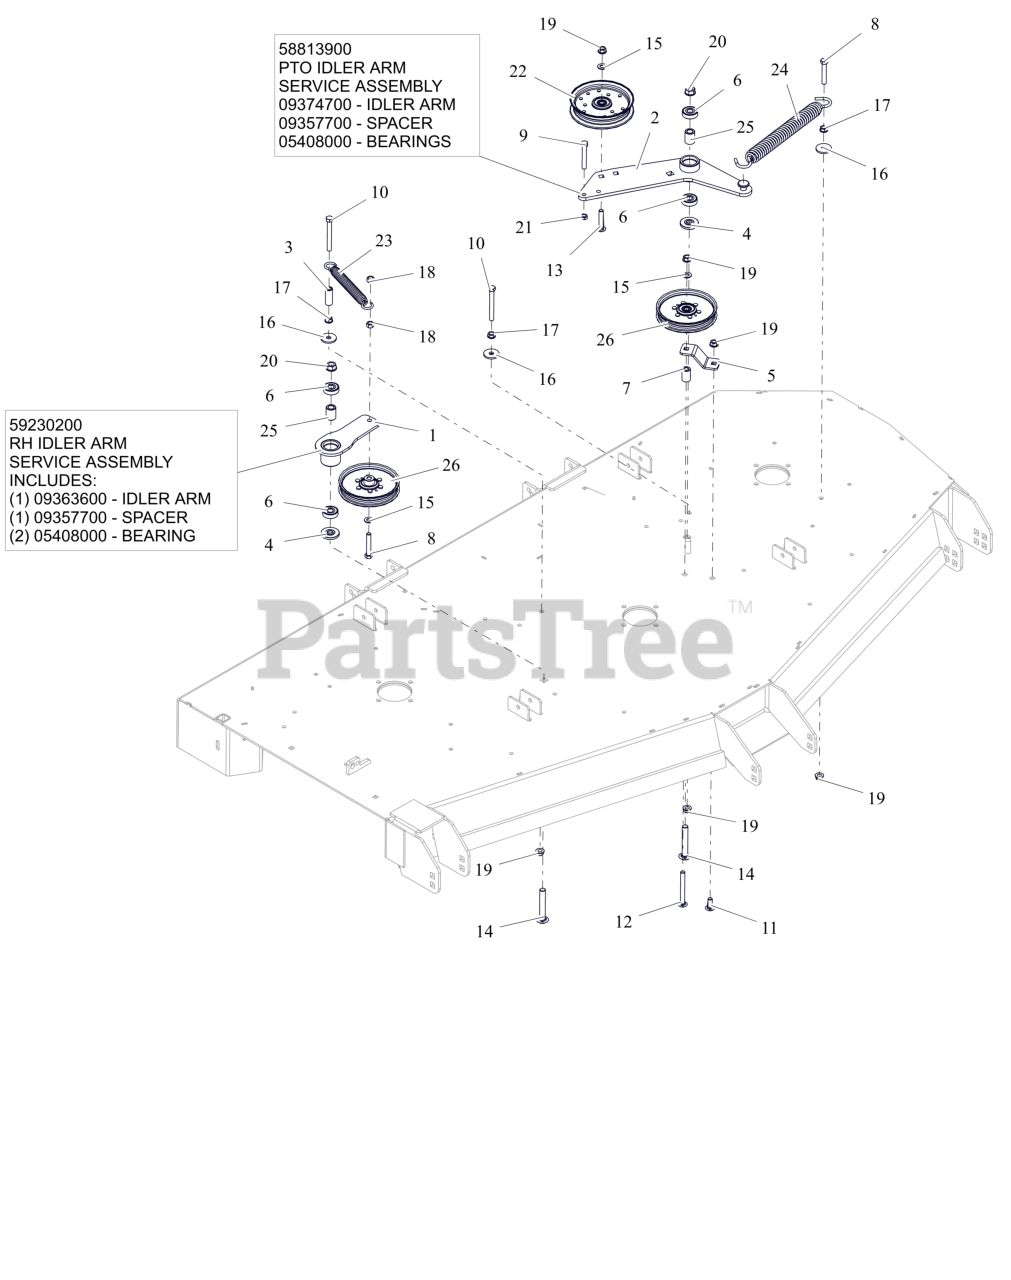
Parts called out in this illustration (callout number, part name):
1	WLDMT, DECK RH IDLER ARM
1	RH IDLER ARM
1	SPACER .510 X .75 X 1.1485
1	BRG-BALL .500X1.38X.437
2	WLDMT, IDLER ARM PT660
2	PTO IDLER ARM
2	SPACER .510 X .75 X 1.1485
2	BRG-BALL .500X1.38X.437
3	SPACER, .375IDX.625ODX1.66 PM
4	SPACER, IDLER ARM
5	PTO FIXED IDLER MTG BRKT -RED
6	BRG-BALL .500X1.38X.437
7	BUSHING, SLV .380X.750X1.190
8	BLT,HEX .38-16X2.25 G5 ZCC
9	BLT, HEX .38-16X2.50 G5 ZCC
10	BLT, HEX .38-16X3.25 G5 ZCC
11	BLT,RHSSN .38-16X1.00 G5 ZCC
12	BLT,RHSSN .38-16X3.50 G5 ZCC
13	BLT,RHSSN.375-16X2.00 G5 ZCC
14	BTL,RHSSN .500-13 X 3.25 G5 ZCC
15	WSHR,FLT .406X.812X.065 ZCC
16	WSHR,FLT .406X1.375X.135 ZCC
17	NUT, SPNLK-FLG .38-16 G5 ZCC
18	NUT-LK-CTR .38-16 ZC120
19	NUT-LK-CTR-FLG .375-16 GF ZCC
20	NUT-LK-CTR-FLG .500-13 GG ZCC
21	NUT-JAM .375-16 G2 ZCC
22	PULLEY, FLAT IDLER .500 X .375 W/BRG
23	SPRING, EXTENSION
24	SPRING, EXTENSION
25	SPACER .510 X .75 X 1.1485
26	PULLEY, FLAT IDLER
